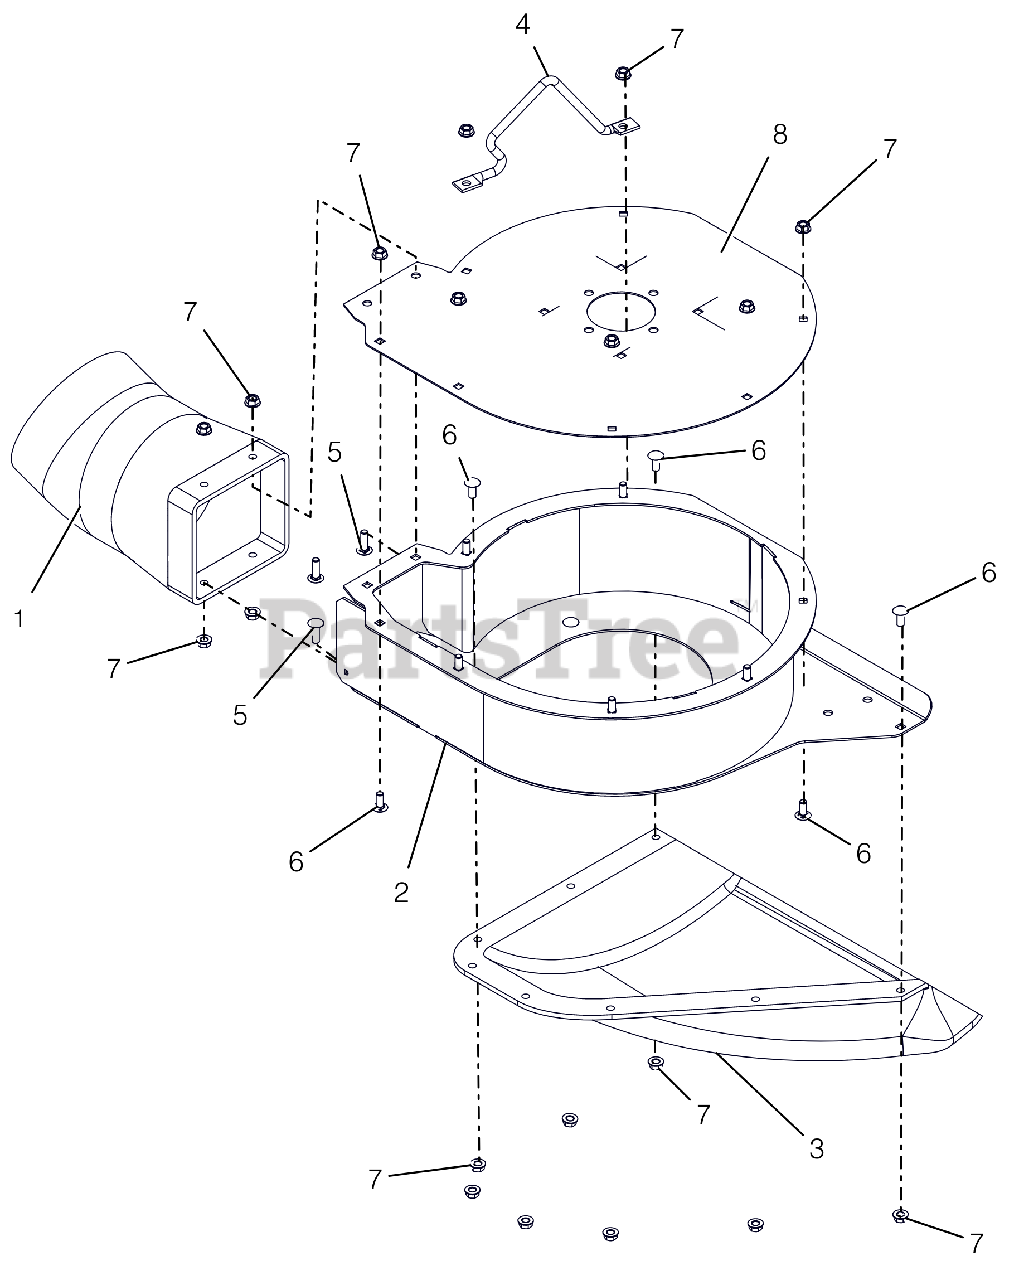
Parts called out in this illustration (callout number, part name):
1	ADAPTER, HOSE
2	WLDMT, BLOWER
3	PLENUM, GRASS PUMP
4	HANDLE, BOLT-ON
5	@BLT-RHDSSQNK .31-18X1.00 G5YZ
6	@BLT-RHDSSQNK .31-18X.75 G5YZ
7	@NUT-LK-TOP-FLG .31-18 YWZC
8	COVER, BLOWER HSG W/SAFETY
